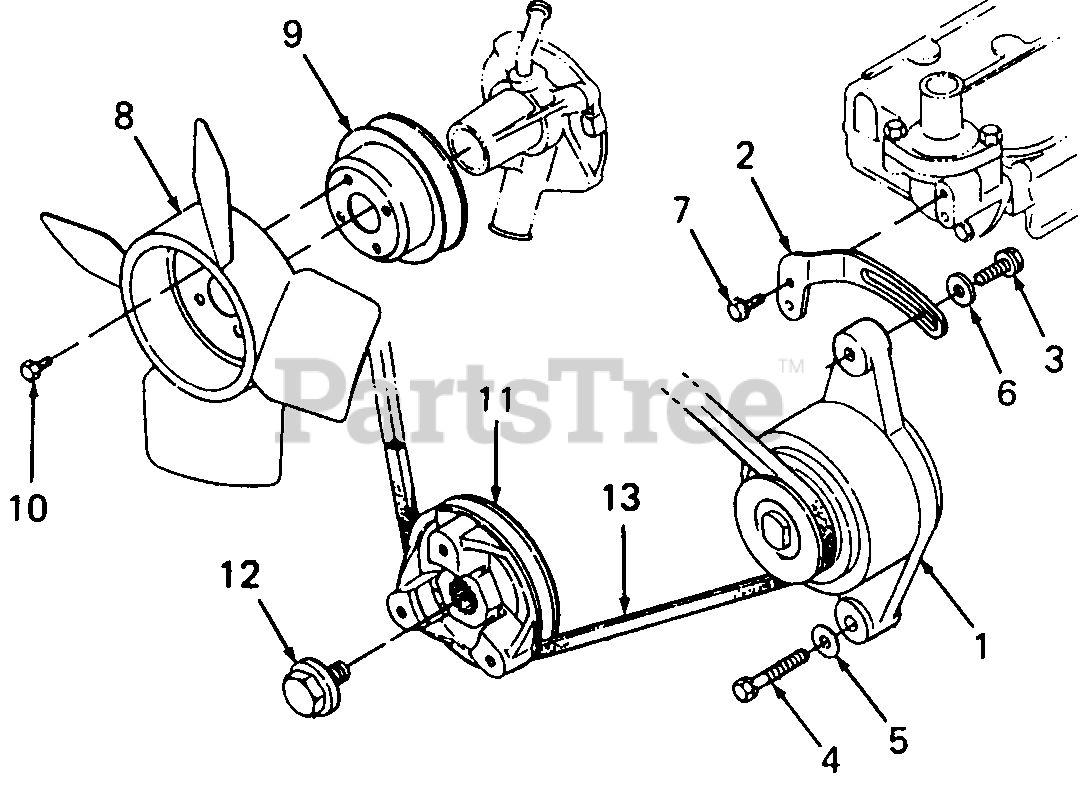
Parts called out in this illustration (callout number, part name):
1	Alternator Assy
2	Stay, Alternator
5	Washer, Plain
6	Washer, Plain
11	Pulley, Fan Drive
